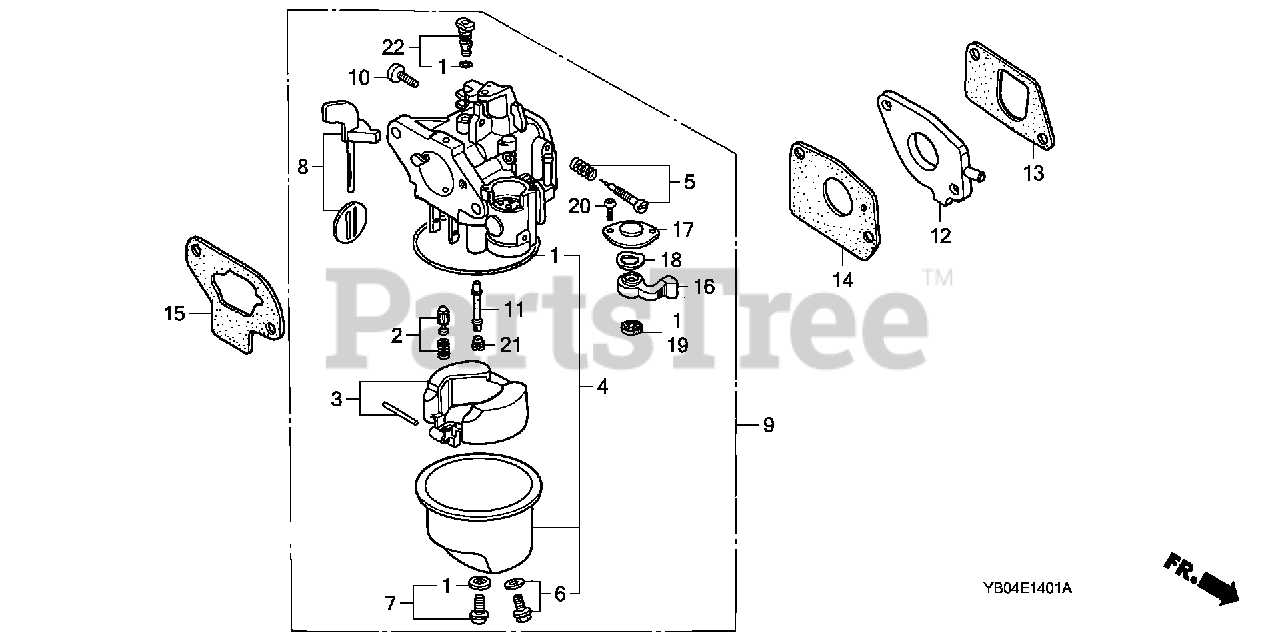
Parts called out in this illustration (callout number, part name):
1	GASKET SET
2	VALVE SET, FLOAT
4	CHAMBER SET, FLOAT
5	SCREW SET, PILOT
5	SCREW SET
6	SCREW SET, DRAIN
7	SCREW SET
9	CARBURETOR ASSY. (BF12A B)
9	CARBURETOR ASSY. (BF12B C)
10	SCREW, THROTTLE STOP
11	NOZZLE, MAIN
12	INSULATOR, CARBURETOR
13	GASKET, INSULATOR
14	GASKET, CARBURETOR
15	GASKET, AIR CLEANER
16	LEVER, VALVE
17	PLATE, LEVER SETTING
18	SPRING, VALVE LEVER
19	GASKET, VALVE
20	SCREW, PAN (3X6)
21	JET, MAIN (#50) Use from Engine SN BF12A B.
21	JET, MAIN (#52) Use from Engine SN BF12A B.
21	JET, MAIN (#55)
21	JET, MAIN (#52) Use up to Engine SN BF12B C.
21	JET, MAIN (#55) Use up to Engine SN BF12B C.
21	JET, MAIN (#58)
22	JET SET, PILOT (#35)
22	JET SET, PILOT (#38)
22	JET SET, PILOT (#40)
